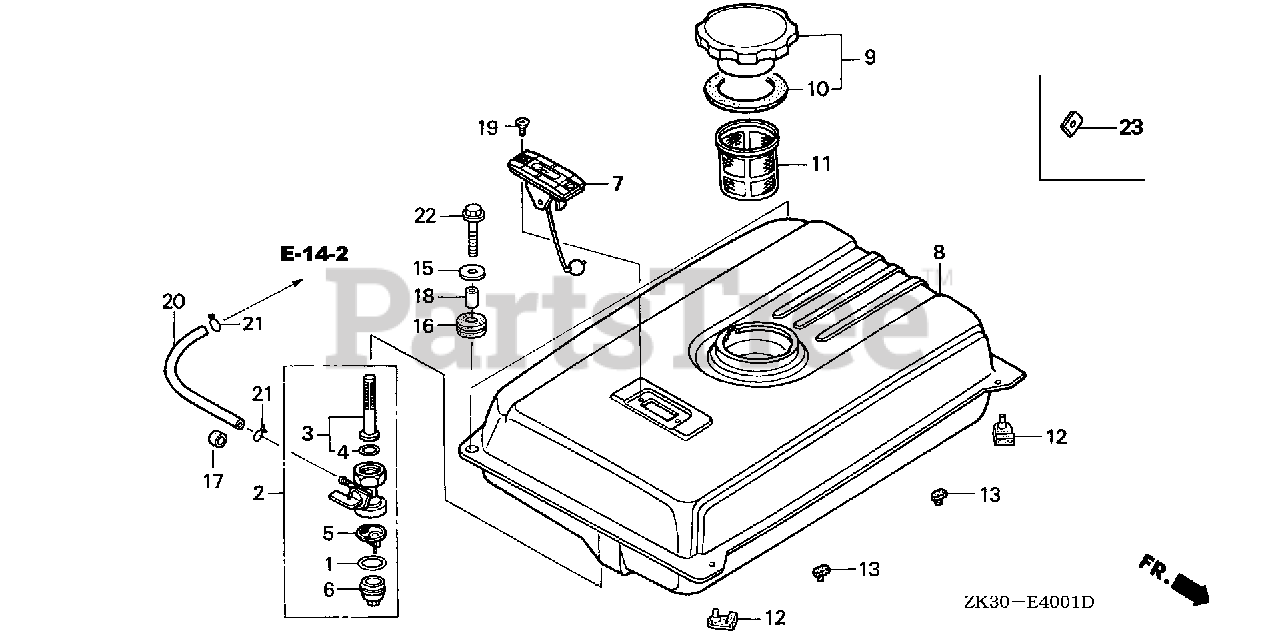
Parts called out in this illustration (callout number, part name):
1	GASKET, FUEL STRAINER CUP
2	PETCOCK ASSY.
3	SCREEN SET, FUEL STRAINER
4	O-RING (9.0X1.3)
5	FILTER, CUP
6	CUP, FUEL STRAINER
7	METER ASSY., FUEL
8	TANK, FUEL *T68* (TSURUMI BLUE)
9	CAP, FUEL FILLER
10	GASKET, FUEL FILLER CAP
11	FILTER, FUEL
12	RUBBER, TANK MOUNTING
13	STOPPER, DISCHARGE GUARD
15	WASHER, TANK CUSHION
16	RUBBER, TANK CUSHION
17	RUBBER, FUEL (9X15X10)
18	COLLAR, TANK CUSHION
19	SCREW, FLAT (5X10)
20	BULK HOSE, FUEL (4.5X3000) (4.5X150)
21	CLIP, TUBE (B8)
22	BOLT, FLANGE (6X22)
